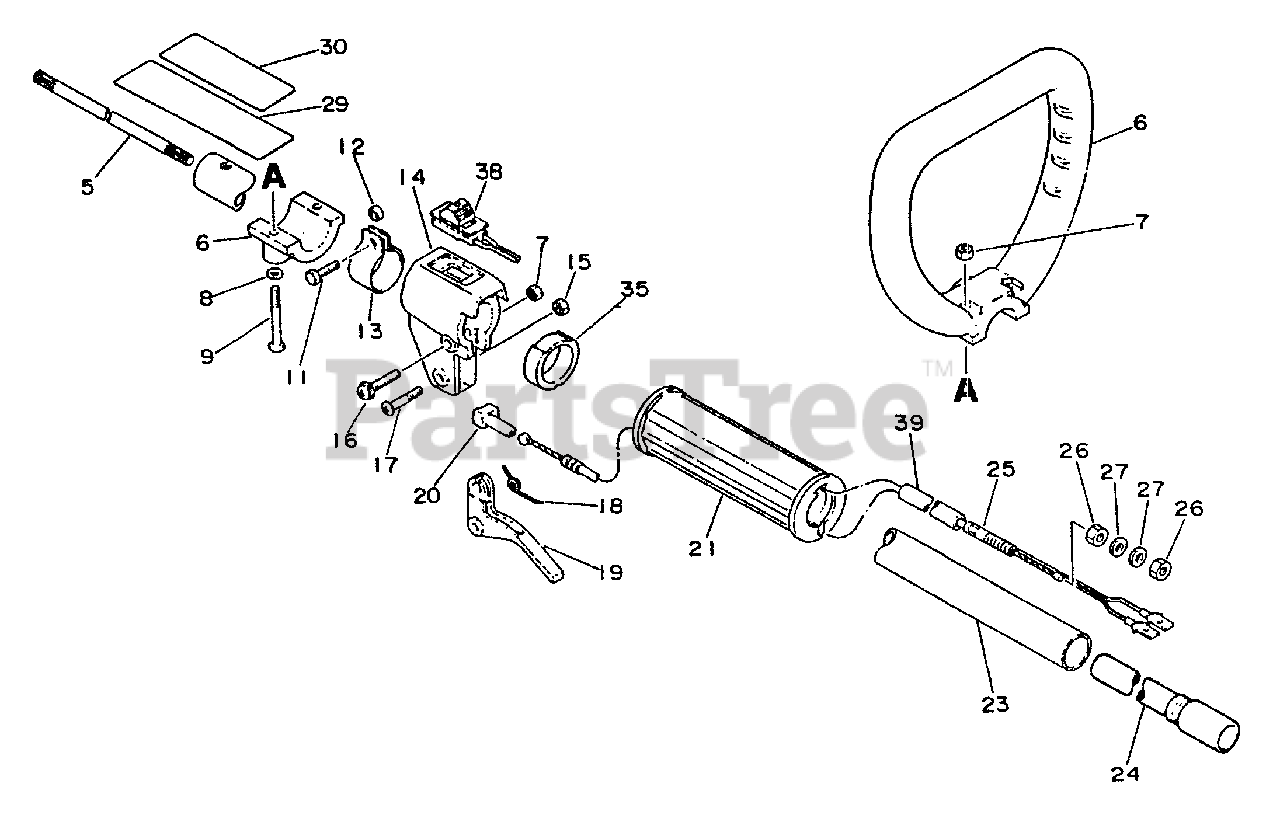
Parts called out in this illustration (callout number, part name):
5	DRIVESHAFT - FLEXIBLE
6	LOOP HANDLE ASSY
8	WASHER - 5
9	SCREW - 5X40
11	BOLT - 5X18
14	BRACKET, THROTTLE CONTROL
15	LOCKNUT - 5
16	SCREW - 5X30
17	SCREW - 5X30
18	SPRING, TRIGGER
19	TRIGGER, THROTTLE
20	GUIDE, CABLE
21	GRIP, HANDLE
23	PIPE, MAIN
24	LINER
25	CABLE, THROTTLE
27	WASHER - 6
29	LABEL - CAUTION
30	LABEL - CAUTION
38	IGNITION SWITCH ASSY
39	TUBE - VINYL
